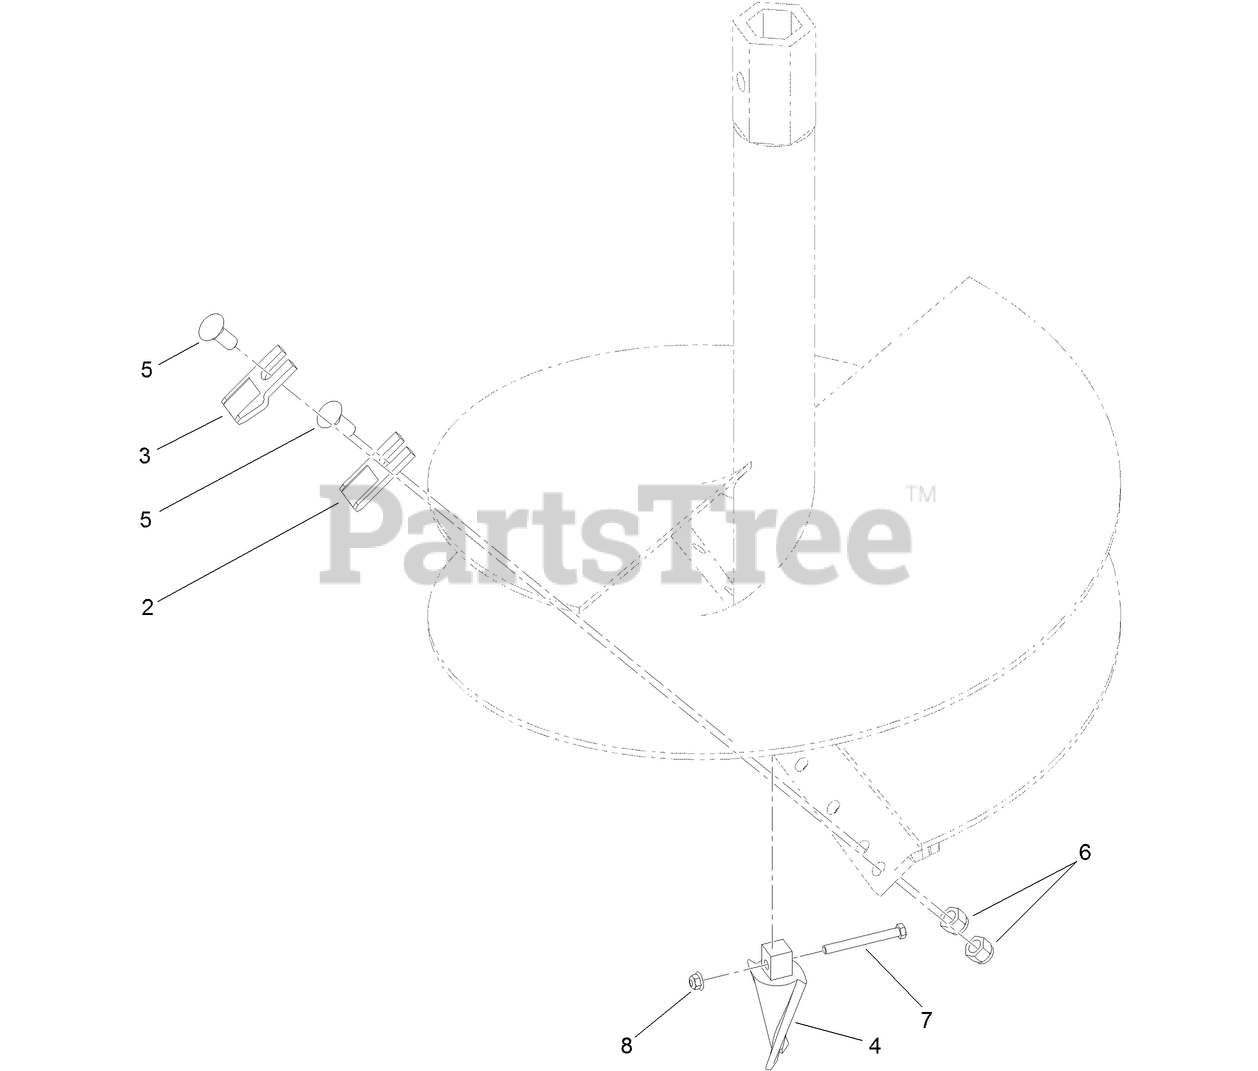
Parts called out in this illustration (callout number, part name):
2	TOOTH-AUGER, WISDOM (INSIDE)
3	TOOTH-AUGER, WISDOM (OUTER)
4	TOOTH-FISHTAIL, STANDARD
5	SCREW-CARRIAGE
6	NUT-LOCK, NI
7	SCREW-HH
8	NUT-HF, NI
